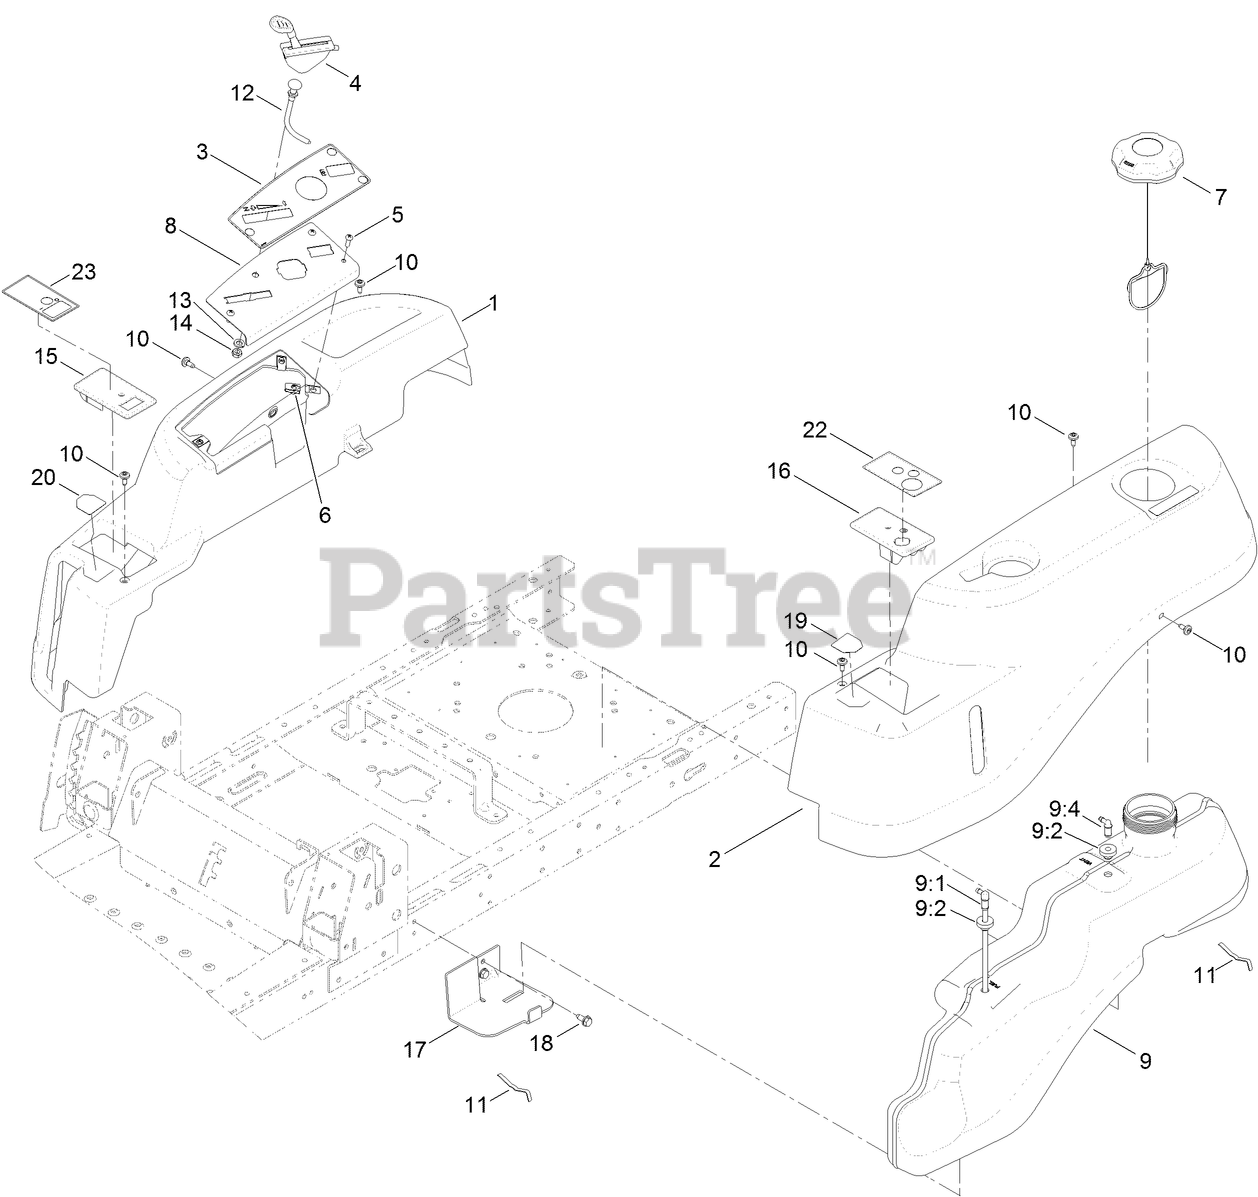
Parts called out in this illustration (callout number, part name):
1	POD-RH
2	POD-LH
3	DECAL-PANEL, CONTROL
4	CABLE-THROTTLE
5	SCREW-PRH
8	PLATE-CONTROL
9	FUEL TANK ASM
9:1	CONNECTOR-ELBOW, 90 DEG
9:2	BUSHING
9:4	FITTING-PLASTIC
10	SCREW-SHOULDER
11	SPRING
12	CABLE-CHOKE
13	WASHER-LOCK
14	NUT-HJ
15	COVER-RH
16	COVER-LH
17	SUPPORT-TANK, FRONT
18	SCREW-HWHTF
19	DECAL-NMIR
20	DECAL-CONTROL, PEDAL
22	DECAL-KEYCHOICE
23	DECAL-BRAKE, PARKING
